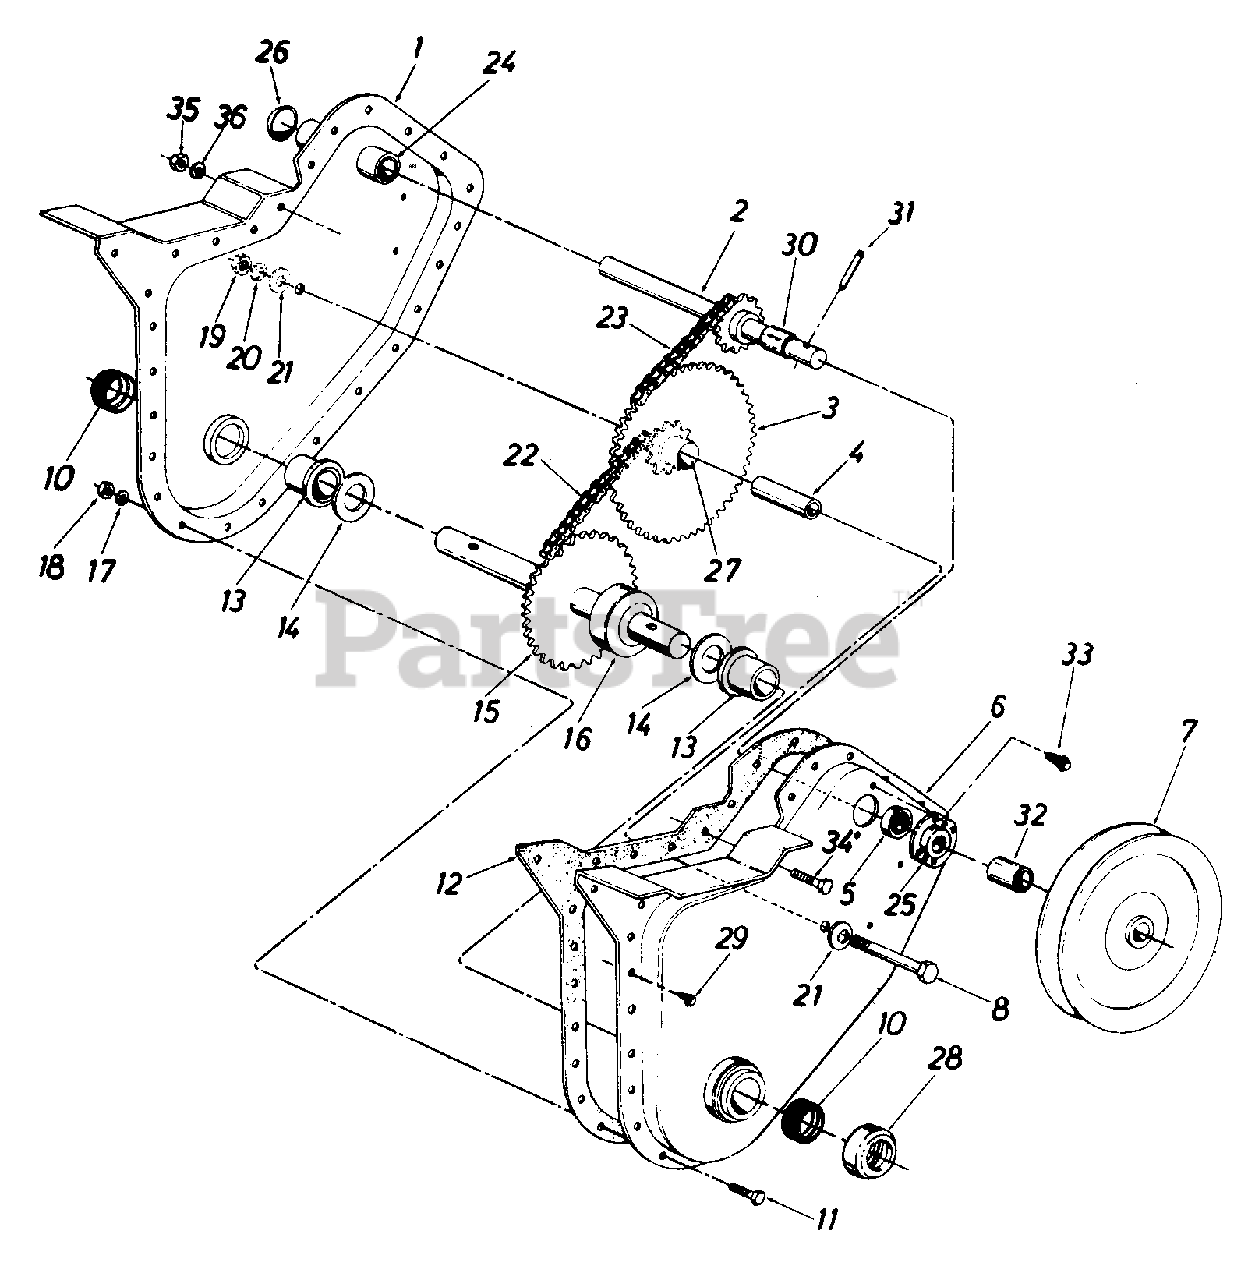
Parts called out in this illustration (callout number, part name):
1	Chain Case Ass'y. R.H.
2	Input Shaft Ass'y.
3	Hub and Sprocket Ass'y.
4	Bearing Inner Race
5	Ball Bearing
6	Chain Case Ass'y. L.H.
7	Pulley Chain Case
8	Hex Bolt 3/8-24 x 2.5 Lg.
11	Hex Bolt 1/4-28 x .625" Lg.
12	Gasket
13	Flange Brg. .879" I.D.
14	Fl-Wash. .88" I.D. x 1.5"
15	Tine Shaft Ass'y.
16	Spacer 7/8" I.D. x 2" O.D. x.68" Lg.
17	L-Wash. 1/4" I.D.
18	Hex Nut 1/4-28 Thd.
19	Hex Ins. L-Nut 3/8-24 Thd.
20	L-Wash. 3/8" I.D.
21	Bell-Wash. .406" I.D.
22	Chain #4201/2" Pitch x 37 Links
23	Chain #35 .375" Pitch x 49 Links
24	Bearing .62" I.D. x .813"
25	Bearing Housing
26	Expansion Plug 13/16" Dia.
27	Bearing
28	Dust Cap
29	Hex Wash. Hd. Self-Tap Scr. 1/4-20 x .50" Lg.
30	Spacer .63" I.D. x .77" O.D. x .38" Lg.
31	Spring Pin Spiral 1/4" Dia. x 1 1/2" Lg.
32	Spacer .647 x 1.25
33	Hex Wash. Hd. Self-Tap Scr. 1/4-20 x .38" Lg.
34	Hex Bolt 5/16-18 x .75" Lg.*
35	Hex Nut 5/16-18 Thd.*
36	L-Wash. 5/16" I.D.*
